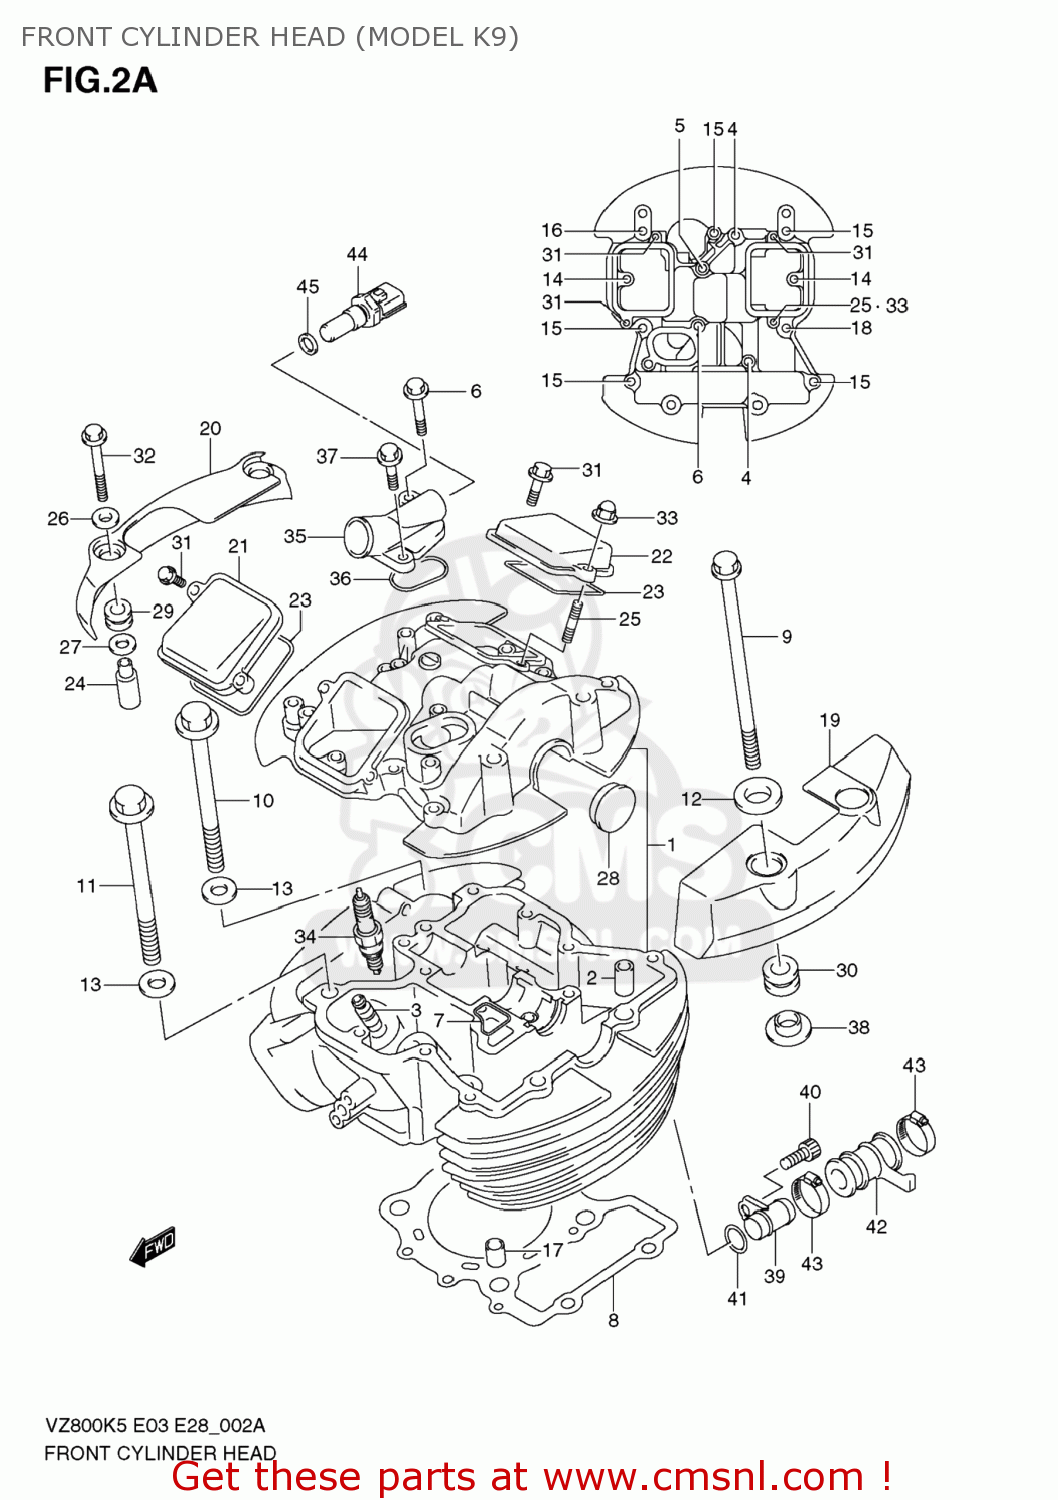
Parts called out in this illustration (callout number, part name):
1	HEAD ASSY,CYLINDER FR
2	PIN(8.4X11X14)
3	GUIDE,VALVE(OS:0.3)
4	BOLT(6X50)
5	BOLT(6X55)
6	BOLT
7	GASKET,CYLINDER HEAD WATER (NAS)
8	GASKET,CYLINDER HEAD FR (NAS)
9	BOLT(8X250)
10	BOLT(10X155)
11	BOLT(10X165)
12	WASHER(8.5X24X1.6)
13	WASHER(10.5X22X2.3)
14	BOLT
15	BOLT
16	BOLT
17	PIN
18	BOLT
19	CAP,CYLINDER HEAD COVER FR,L
20	CAP,CYLINDER HEAD COVER FR
21	CAP,INSPECTION INTAKE
22	CAP,INSPECTION EXHAUST
23	GASKET,INSPECTION CAP (NAS)
24	SPACER,CYL HEAD COVER CAP NO.2
25	BOLT,STUD
26	WASHER(6.5X18X1.6)
27	WASHER(9.5X20X1)
28	PLUG(OD:30)
29	CUSHION
30	CUSHION
31	BOLT
32	BOLT
33	NUT
34	PLUG,SPARK(DR8EA)
35	UNION,CYL HEAD OUTLET
36	GASKET,WATER OUTLET UNION (NAS)
37	BOLT
38	BUSH
39	UNION,CYL HEAD JOINT
40	BOLT
41	O RING(D:2.4,ID:15.8)
42	HOSE,CYLINDER HEAD JOINT
43	CLAMP
44	SENSOR,WATER TEMP
45	GASKET(12X17X1) (NAS)
